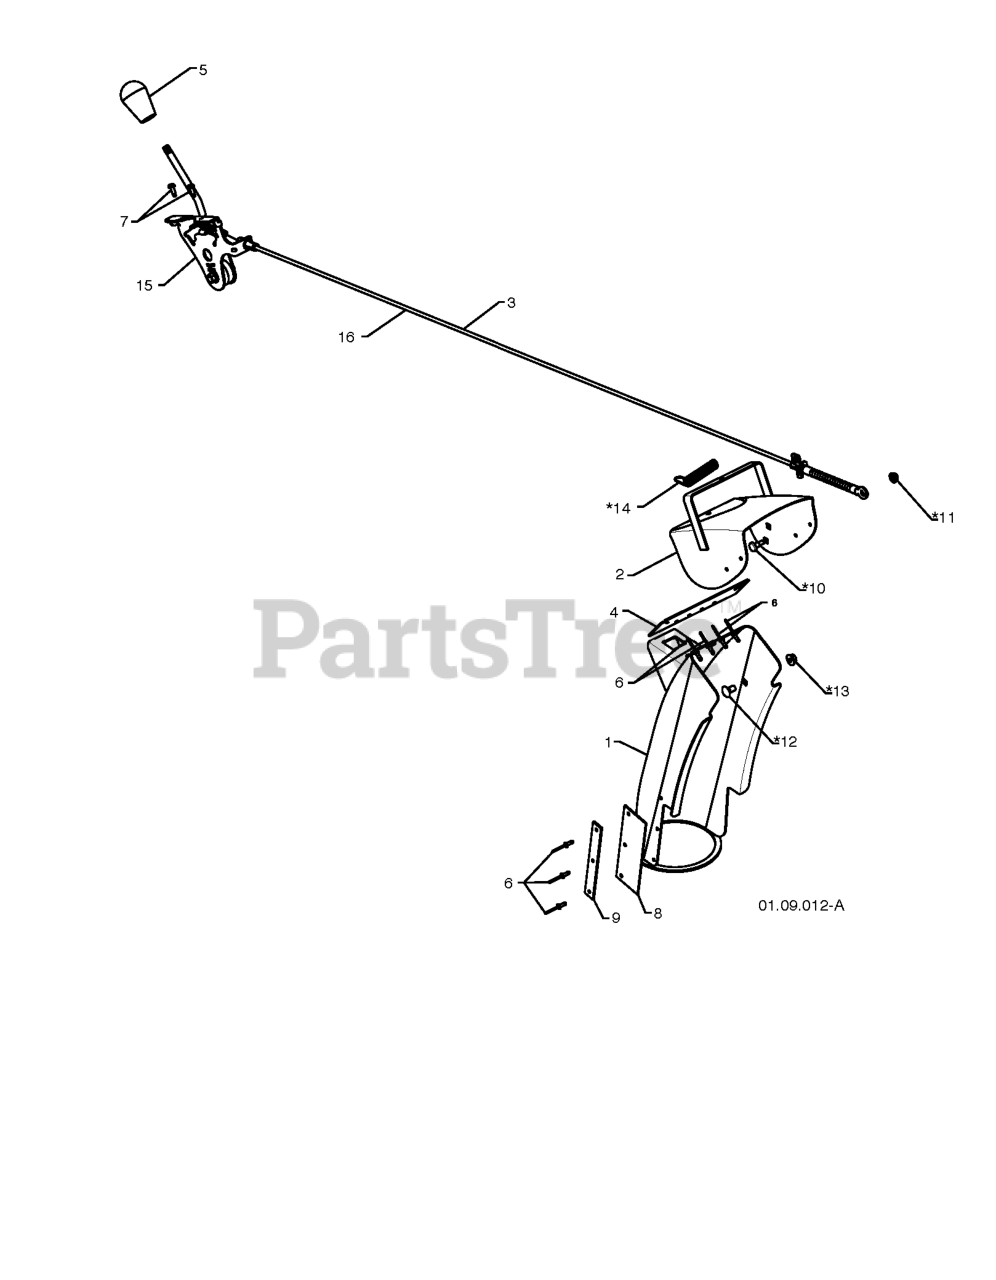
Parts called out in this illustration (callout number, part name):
1	CHUTE.WELDMENT
2	DEFLECTOR.WELDMENT.PNT.ORANGE
3	CONTROL.ASM.DEFLECTOR
4	SEAL.DEFLECTOR
5	KNOB LEVER, BLACK
6	RIVET BLIND
7	SCREW #10-24 X 5/8
8	SHIELD.SNOW.CHUTE
9	STRAP.SHEILD.RETAINER
10	BOLT, SHOULDER
11	NUT.HEX.FLANGE.1/4
12	BOLT
13	NUT.LOCK.5/16-18
14	SPRING.DEFLECTOR.REM.CHUTE
15	RP CNTRL.HEAD.ASSEM.DEFLECTOR
16	SERVICE.CHUTE.DEF.CBL.GRY
